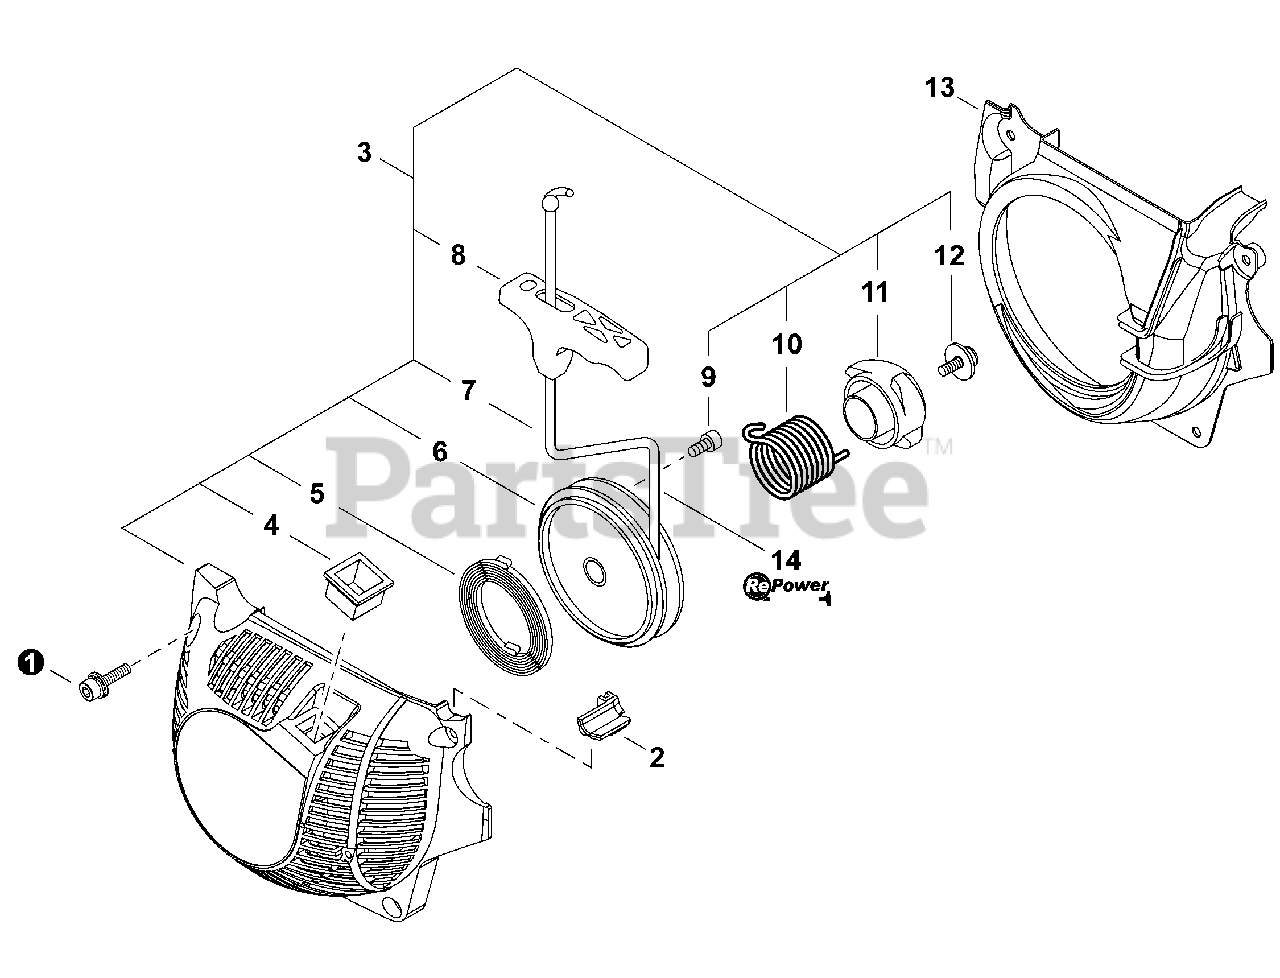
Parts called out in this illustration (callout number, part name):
1	BOLT M4×16
2	GROMMET, NEEDLE
3	STARTER ASSY, RECOIL
4	GUIDE, ROPE
5	SPRING
6	REEL, ROPE
7	ROPE, STARTER
8	GRIP, STARTER
9	BOLT 4×10
10	SPRING, TORSION
11	PAWL CATCHER
13	COVER, FAN
14	ROPE, STARTER - REPOWER BULK
